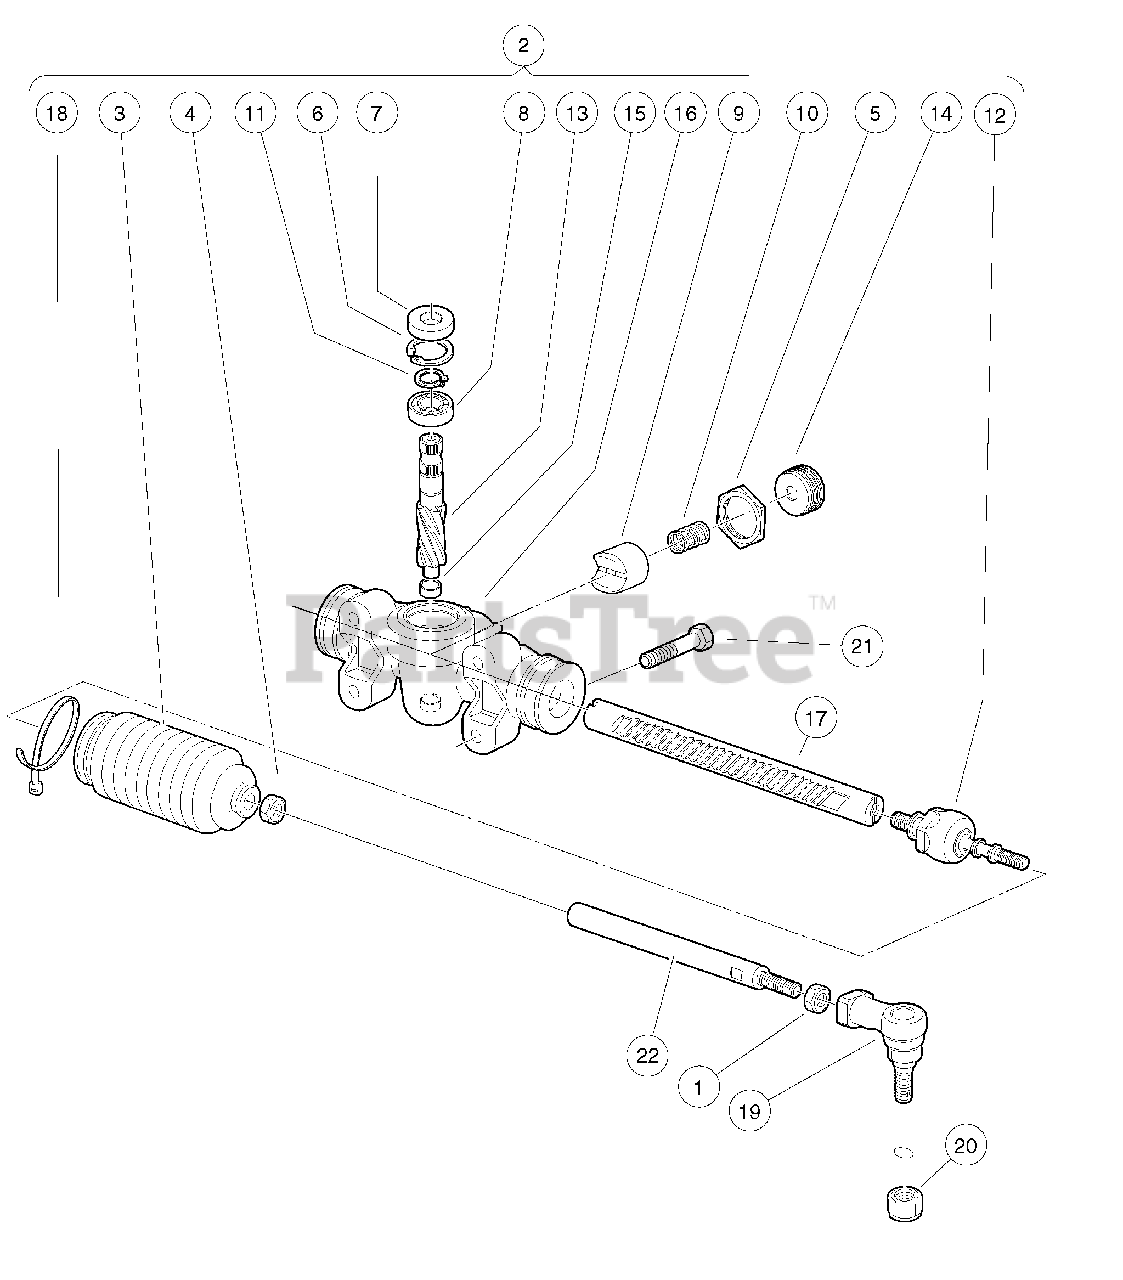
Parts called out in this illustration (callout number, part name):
1	Nut, 12mm Hex
2	Steering Rack
3	Bellows, Long
4	Nut, 12mm Hex
5	Rack Screw Locknut
6	Snap Ring
7	Seal, Steering Pinion Dust
8	Bearing, Ball
9	Support Yoke
10	Rack Guide Pressure Spring
11	Ring, Stop, C-Type
12	Inner Ball Joint Asm
13	Pinion, Steering
14	Bearing, Lower Pinion
15	Screw, Rack Guide
16	Housing, Steering Gear
17	Rack, Steering
18	Tie Wrap, 8" Nylon
19	End, Tie Rod M12 X 1.25
20	Locknut, M12-1.25 Nylon
21	Bolt, Flange Head, M10x 1.5 X 40 with Loctite
22	Link, Drag, Wt
